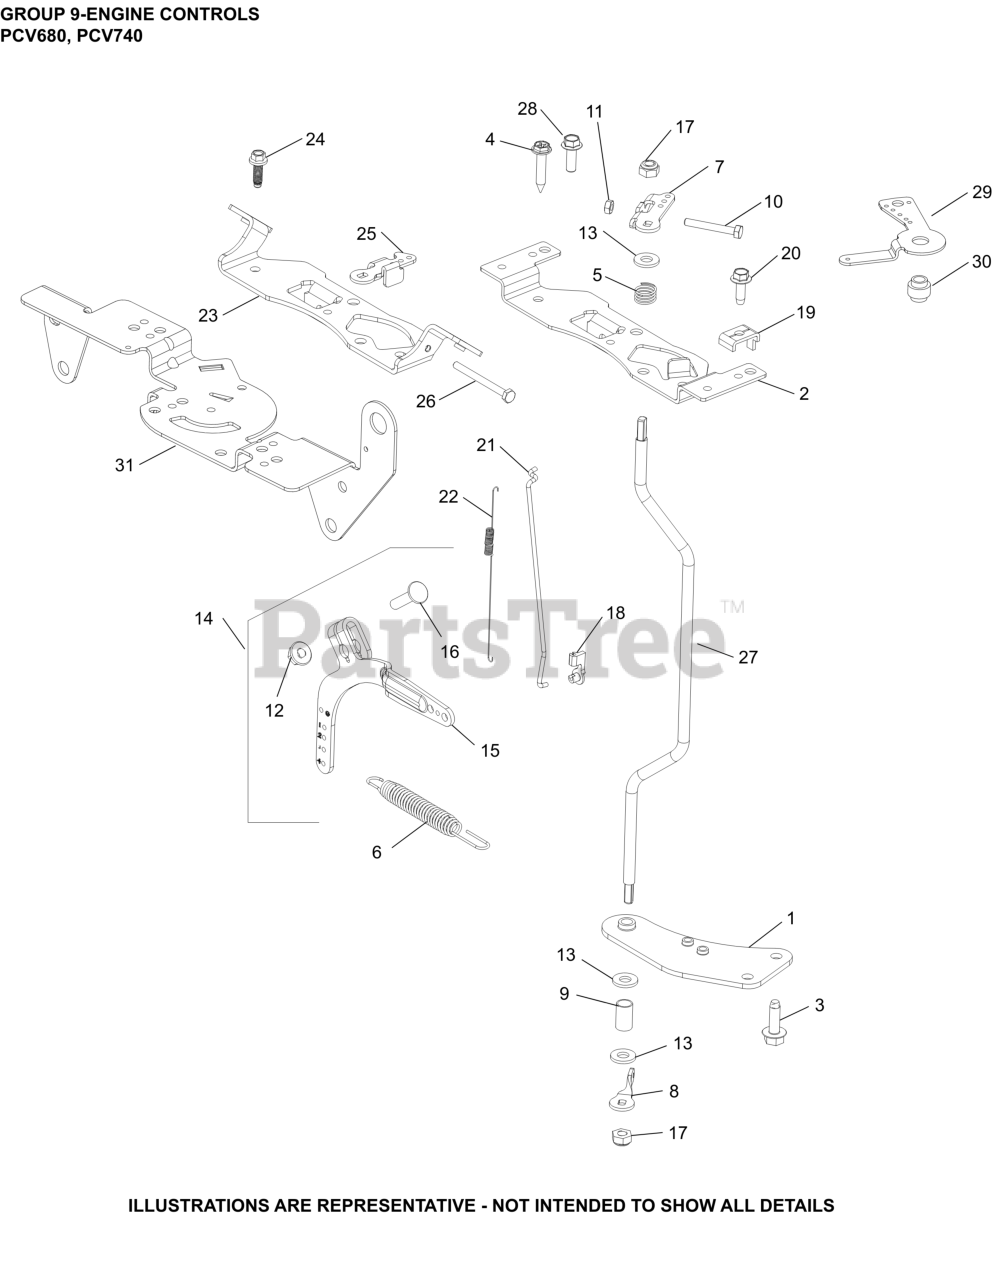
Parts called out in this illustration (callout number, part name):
1	BRACKET, THROTTLE SHAFT
3	SCREW, THREAD FORMING
5	SPRING, THROTTLE SHAFT
6	SPRING, GOVERNOR (BLACK)
8	LEVER, THROTTLE CONTROL
12	NUT, LOCK M6X1.0
13	WASHER, FLAT 1/4"
14	LEVER, GOVERNOR ASSEMBLY
15	LEVER, GOVERNOR - (#2409069S)
16	BOLT, RD HD SQ NECK M6X1.0X25
17	NUT, FLG M6X1.0
18	BUSHING, THROTTLE LINKAGE
21	LINKAGE, THROTTLE
22	SPRING, LINKAGE
23	BRACKET, CONTROL
25	LEVER, THROTTLE CONTROL
26	SCREW, HEX HEAD
27	THROTTLE CONTROL SHAFT
28	SCREW, HI-LOW
NI	SCREW, THREAD FORMING
NI	CLAMP, CABLE
